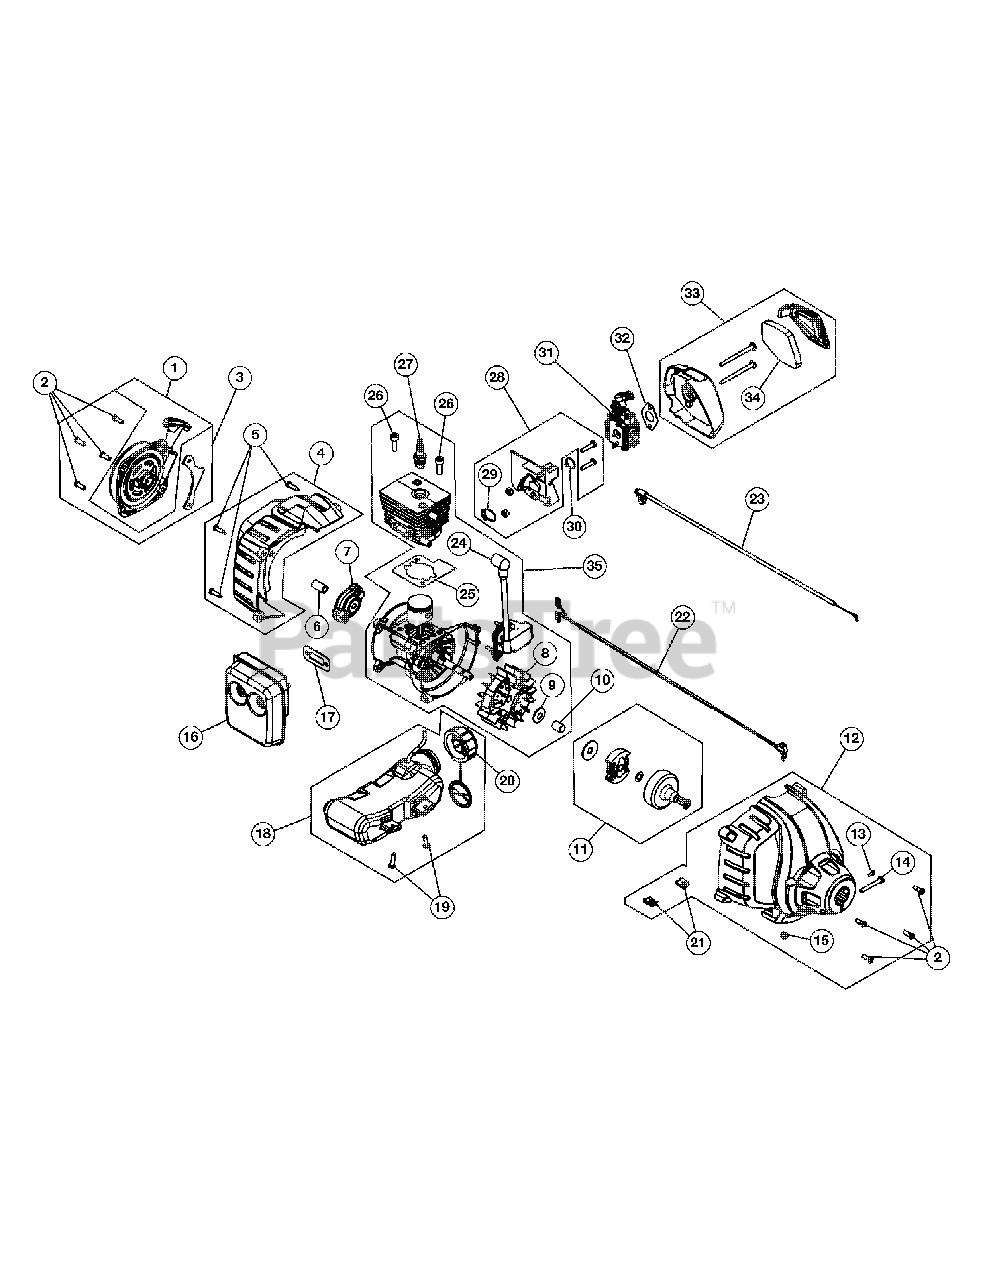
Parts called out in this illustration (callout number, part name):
1	Rear Cover Assembly
2	Starter Screw
3	Starter Assembly Guard
4	Rear Engine Cover
5	Cover Screw
6	Adapter
7	Pawl Assembly
8	Flywheel Assembly
9	Washer
10	Spacer
11	Clutch Assembly
12	Clutch Cover Assembly
13	Anti-Rotation Screw
14	Clamp Screw
15	Clamp Nut
16	Muffler Assembly
17	Muffler gasket
18	Fuel Tank Assembly
19	Tank Screw
20	Fuel Cap
21	U-Shaped Nut
22	Lead Wires
23	Throttle Cable
24	Module Assembly
25	Cylinder Gasket
26	Cylinder Bolt
27	Spark Plug
28	Insulator Assembly
29	Insulator O-Ring
30	Carburetor O-Ring
31	Carburetor
32	Carburetor Gasket
33	Aircleaner Assembly
34	Aircleaner Filter
35	Shortblock Assembly
